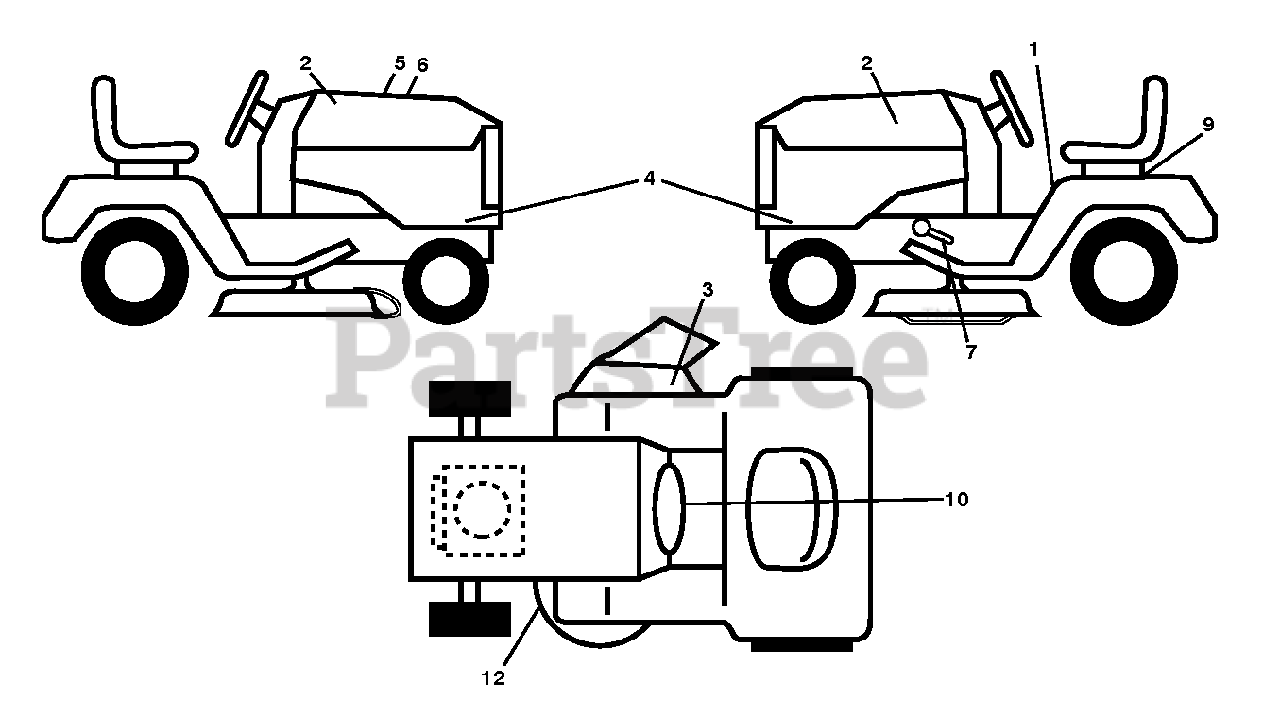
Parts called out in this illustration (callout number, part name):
1	DECAL.FENDER.WARNING.ENGLISH
2	DECAL.BADGE.170MM.TEXTLOGO.
3	DECAL.MOWER.WARN.KEEP.HAND.AWY
4	DECAL HOOD PANEL
5	DECAL.WARNING.CUST.RESP.E85.
6	DECAL.RPL.KW.FR600.TLW.42.K46
7	DECAL.PEDAL.HUSQ.CROWN
9	DECAL BTRY SYMBOLS
10	DECAL, WARNING SPARK ARRESTOR
12	DECAL.V-BELT.SCH.42/46"MEC/ELE
